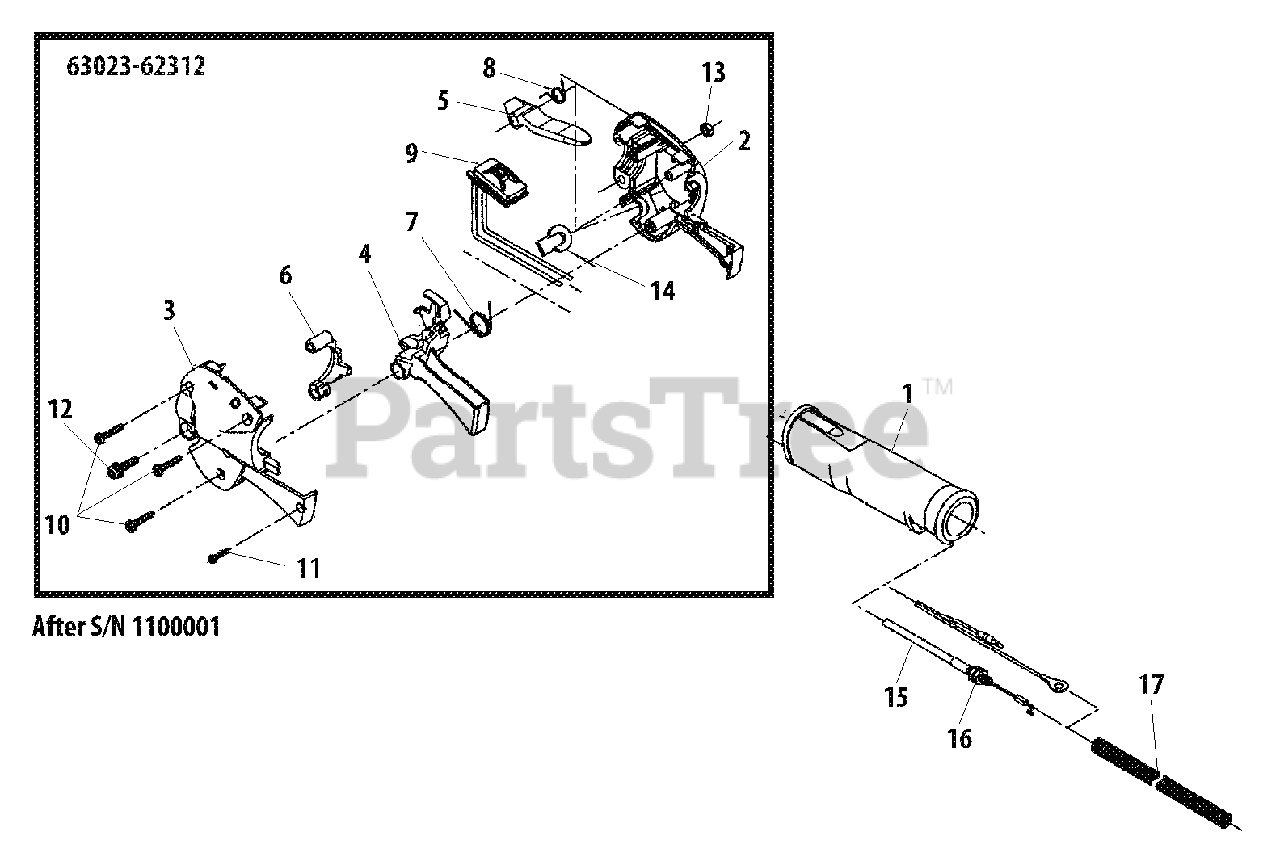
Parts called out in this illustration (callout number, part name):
1	GRIP
2	HANDLE, CONTROL - RIGHT
3	HANDLE, CONTROL - LEFT
4	LEVER
5	LEVER, LOCK
6	HOLDER
7	SPRING
8	SPRING
9	SWITCH, IGNITION
10	SCREW - 4X20 -- TAPPING
11	SCREW - 3X14 -- TAPPING
12	SCREW - 5X20
13	NUT - 5
14	PLUG
15	CABLE, THROTTLE
16	NUT - 6
17	TUBE
63023-62312	THROTTLE LEVER ASSY
